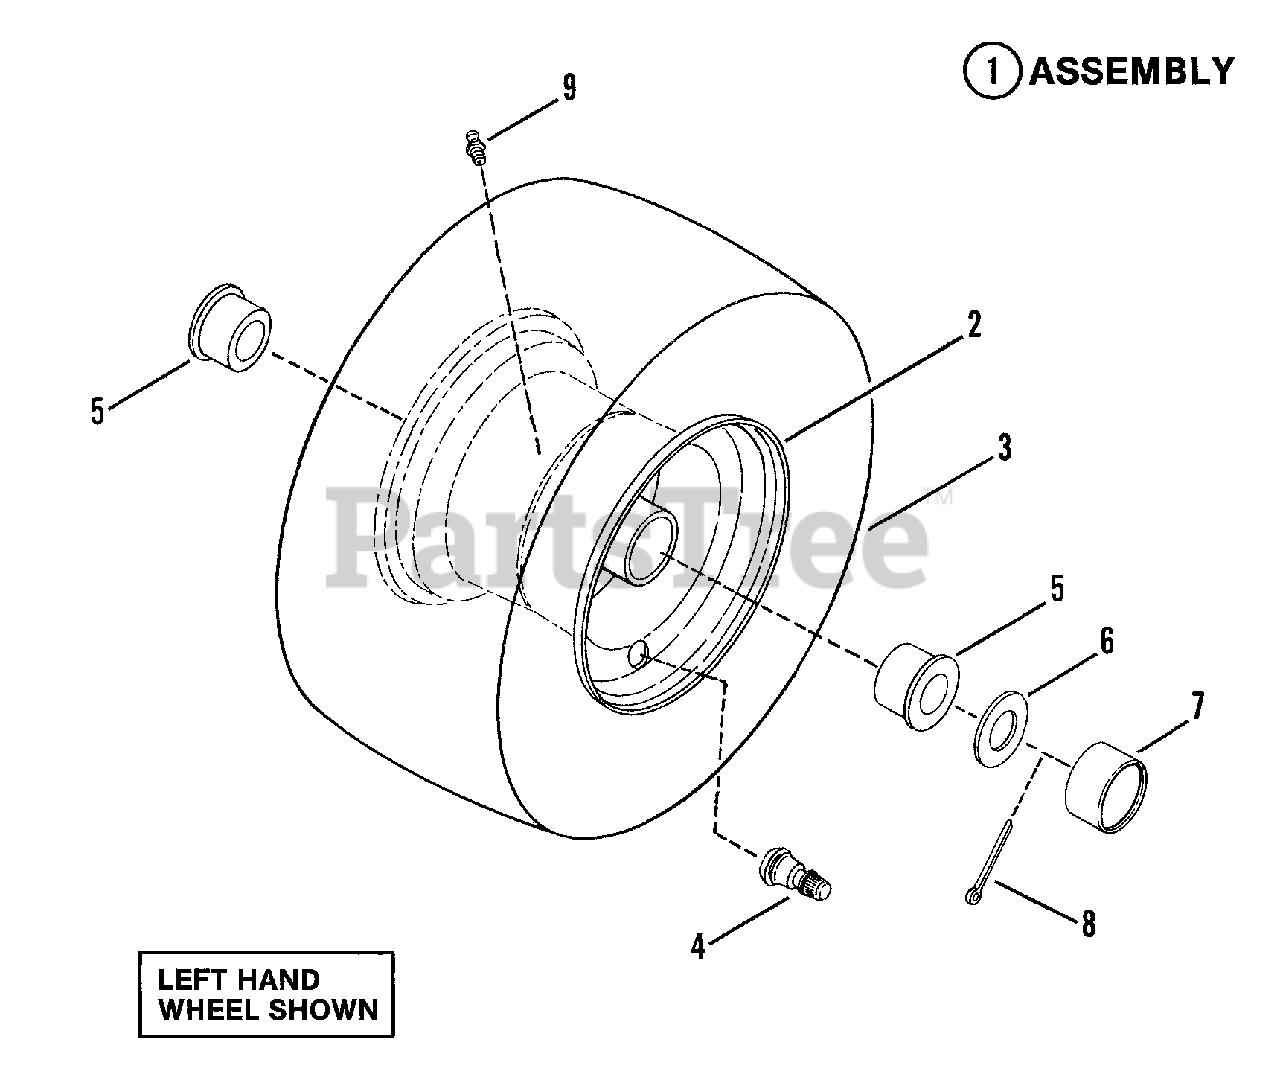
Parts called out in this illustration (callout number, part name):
1	ASSEMBLY, Front tire & Rim
2	RIM, 6x4.50
3	TIRE, 15x6.00x6
4	VALVE, Air
5	BEARING, Wheel
6	WASHER
7	COVER, Dust
8	COTTER-PIN
9	FITTING, Lube 1/4-28 Tapered Thread
